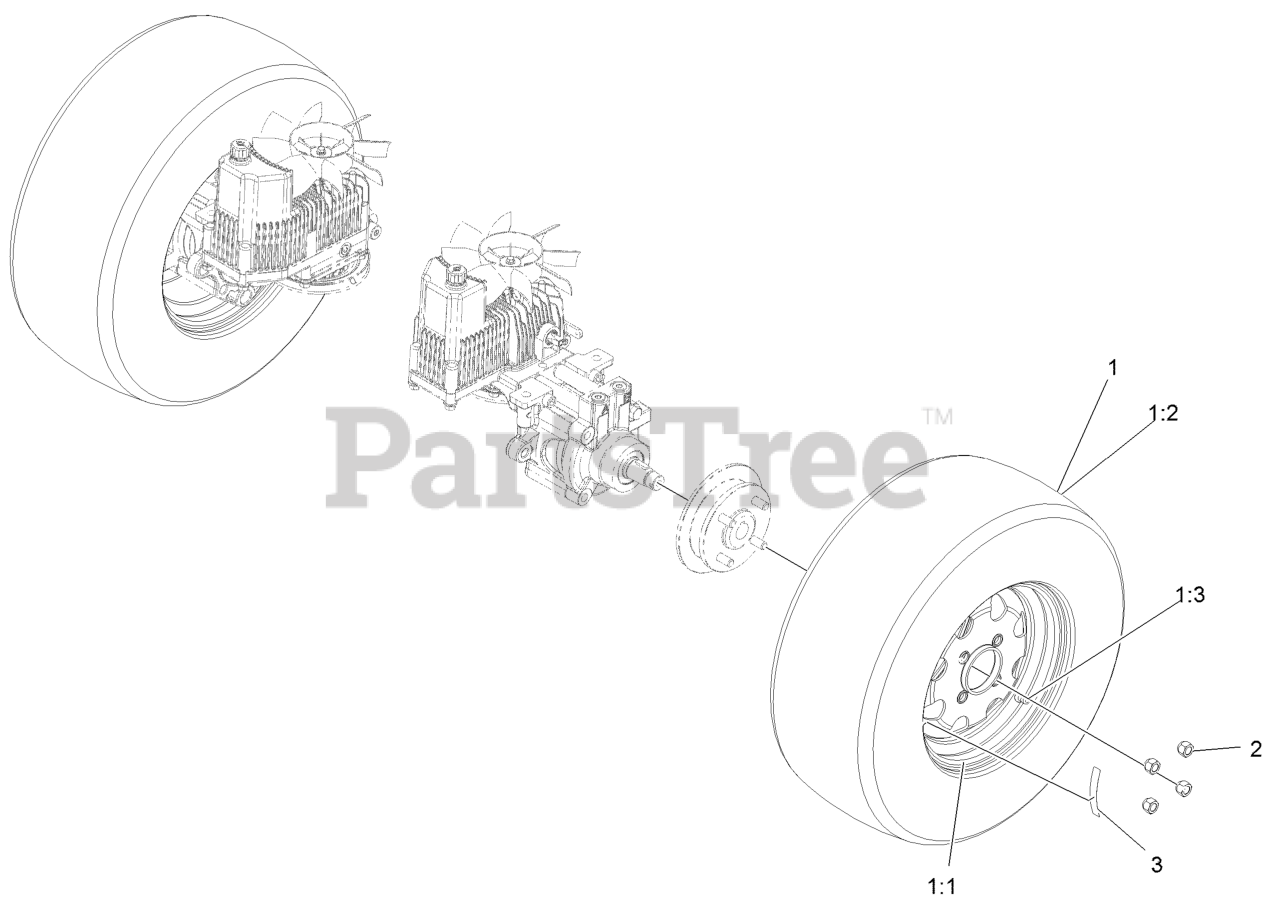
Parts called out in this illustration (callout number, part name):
1	WHEEL AND TIRE ASM
1:1	RIM ASM
1:2	TIRE
1:3	Stem-Valve
2	NUT-LUG
3	DECAL-TORQUE, WHEEL HUB LUG
